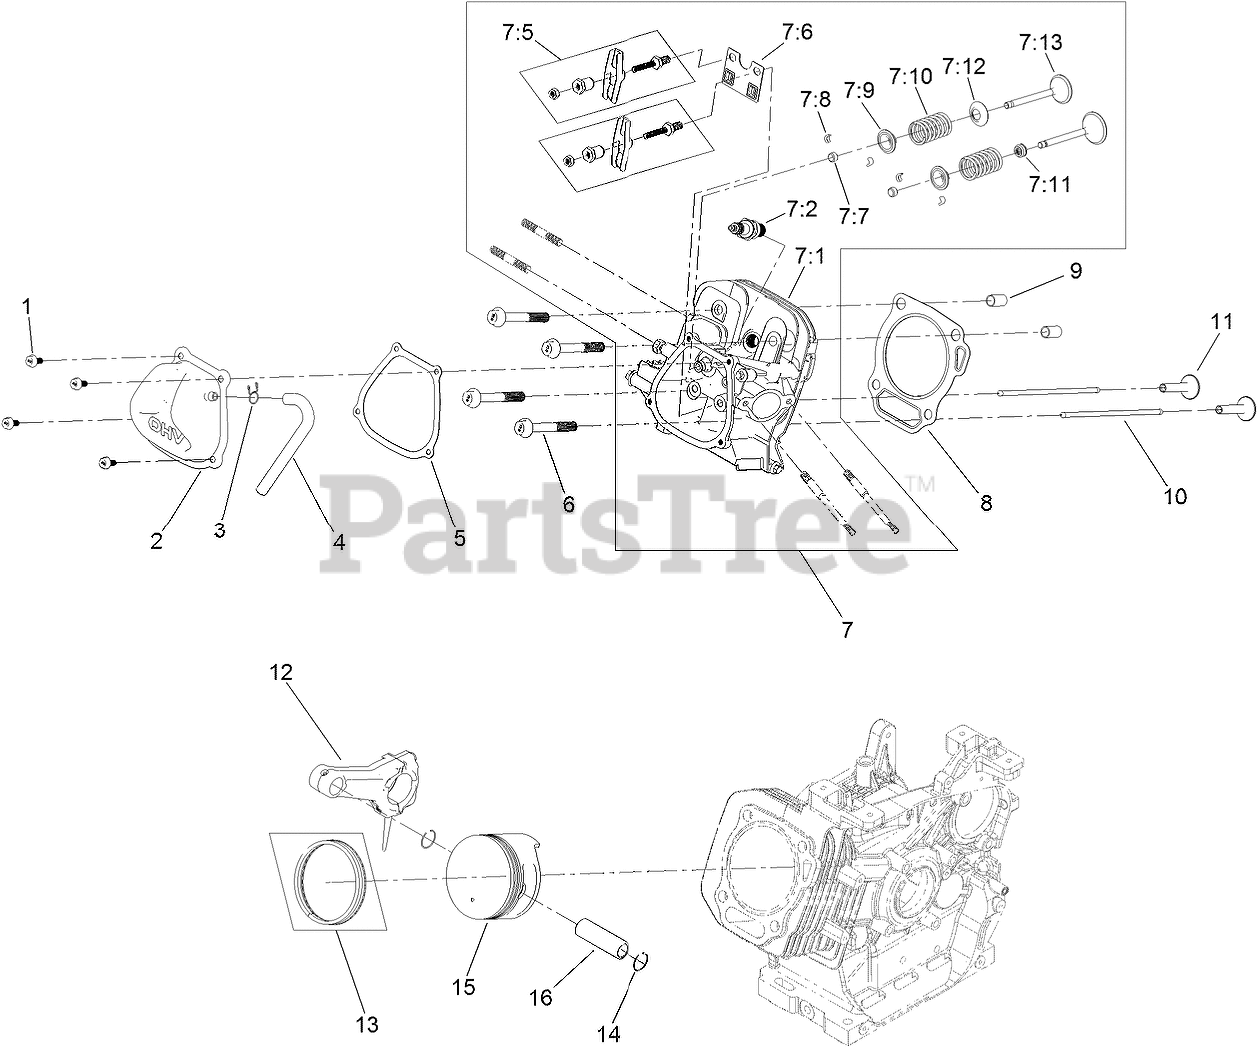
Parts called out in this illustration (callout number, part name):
1	SCREW-HHF
2	VALVE COVER ASM
3	CLAMP-HOSE
4	TUBE-BREATHER
5	GASKET-COVER, VALVE
6	SCREW-HHF
7	COMPLETE HEAD ASM
7:1	HEAD-CYLINDER
7:2	SPARK PLUG
7:5	ROCKER ARM ASM
7:6	PLATE-GUIDE, PUSH ROD
7:7	ROTATOR-VALVE
7:8	KEEPER-VALVE
7:9	RETAINER-SPRING, VALVE
7:10	SPRING-VALVE
7:11	SEAL-STEM, VALVE
7:12	SEAT-SPRING, VALVE
7:13	VALVE SET
8	GASKET-HEAD, CYLINDER
9	PIN-DOWEL
10	ROD-PUSH
11	LIFTER-VALVE
12	CONNECTING ROD ASM
13	RING SET
14	RING-RETAINING, PISTON PIN
15	PISTON
16	PIN-PISTON
